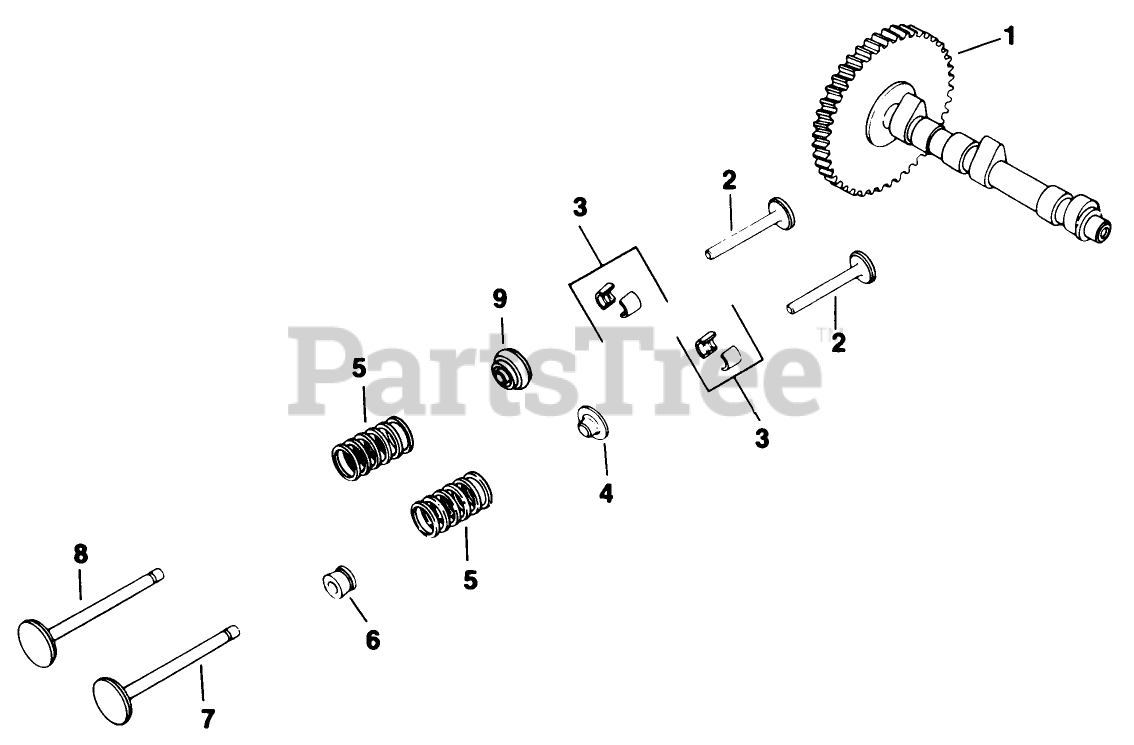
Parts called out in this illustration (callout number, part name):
1	Camshaft
3	Kit-Retainer
4	Retainer-Spring
5	Spring-Valve
6	Seal-Valve Stem
7	Valve-Intake
8	Valve-Exhaust
9	Rotator
